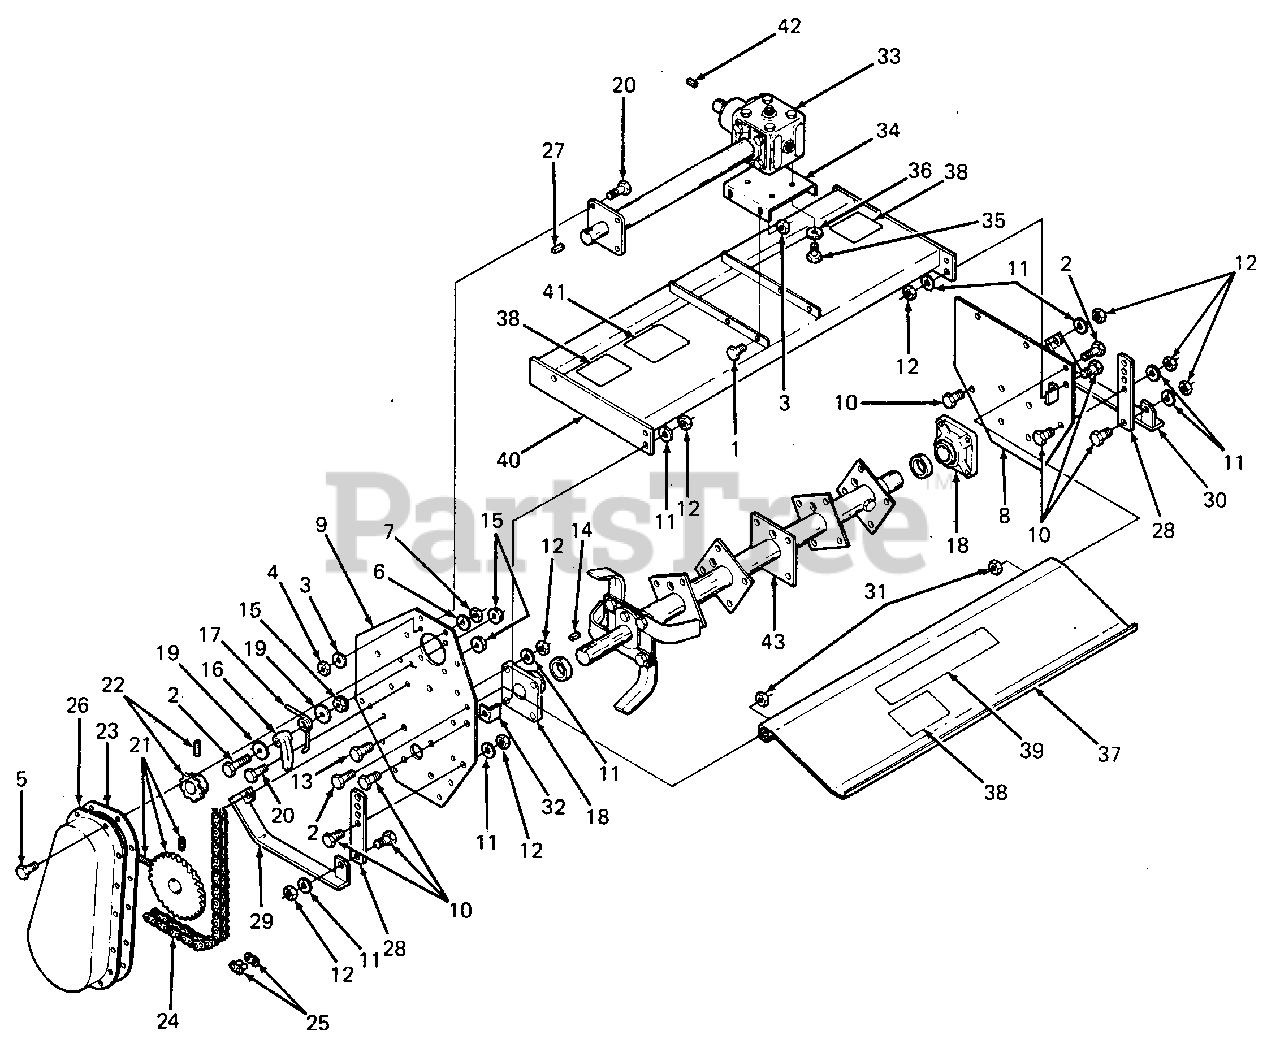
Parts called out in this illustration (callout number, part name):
1	Screw, Hex Cap, 3/8-16 X 3/4 Lg GR 5
2	Screw, Hex Cap, 3/8-16 X 2-1/4 Lg GR 5
3	Washer, Lock, 3/8
4	Nut, Hex, 3/8-16 GR 5
5	Screw, Hex Cap, 5/16-18 X 5/8 Lg GR 5
6	Washer, Lock, 5/16
7	Nut, Hex, 5/16-18 GR 5
8	Plate, RH Side
9	Plate, LH Side
10	Screw, Hex Cap, 1/2-13 X 1-1/4 Lg GR 5
11	Washer, Lock, 1/2
12	Nut, Hex, 1/2-13 GR 5
13	Screw, Hex Cap, 1/2-13 X 1-1/2 Lg GR 5
15	Nut, Whiz, 3/8-16
16	Chain Tensioner
17	Spring, Chain Tensioner
18	Bearing Assy
19	Washer, Flat, 3/8
20	Screw, Hex Cap, 3/8-16 X 1-3/4 Lg GR 5
21	Sprocket 29 Tooth
22	Sprocket 9 Tooth
23	Gasket, Chain Cover
24	Chain, Drive
25	Link, Master
26	Cover, Chain
28	Bar, Depth Adjustment
29	Skid Shoe LH
30	Skid Shoe RH
31	Nut, Lock, 3/8-16
32	Shield Stop
33	Gearbox Assy
35	Screw, Hex Cap, M10 X 25 mm Lg GR 8.8
36	Washer, Lock, M10
37	Rear Shield w/Decals
38	Decal, Danger
39	Decal, Cub Cadet Logo
40	Frame w/Decals (Includes Ref. No. 38 [Qty 2] & 41)
41	Decal, Warning
43	Rotor Assy
